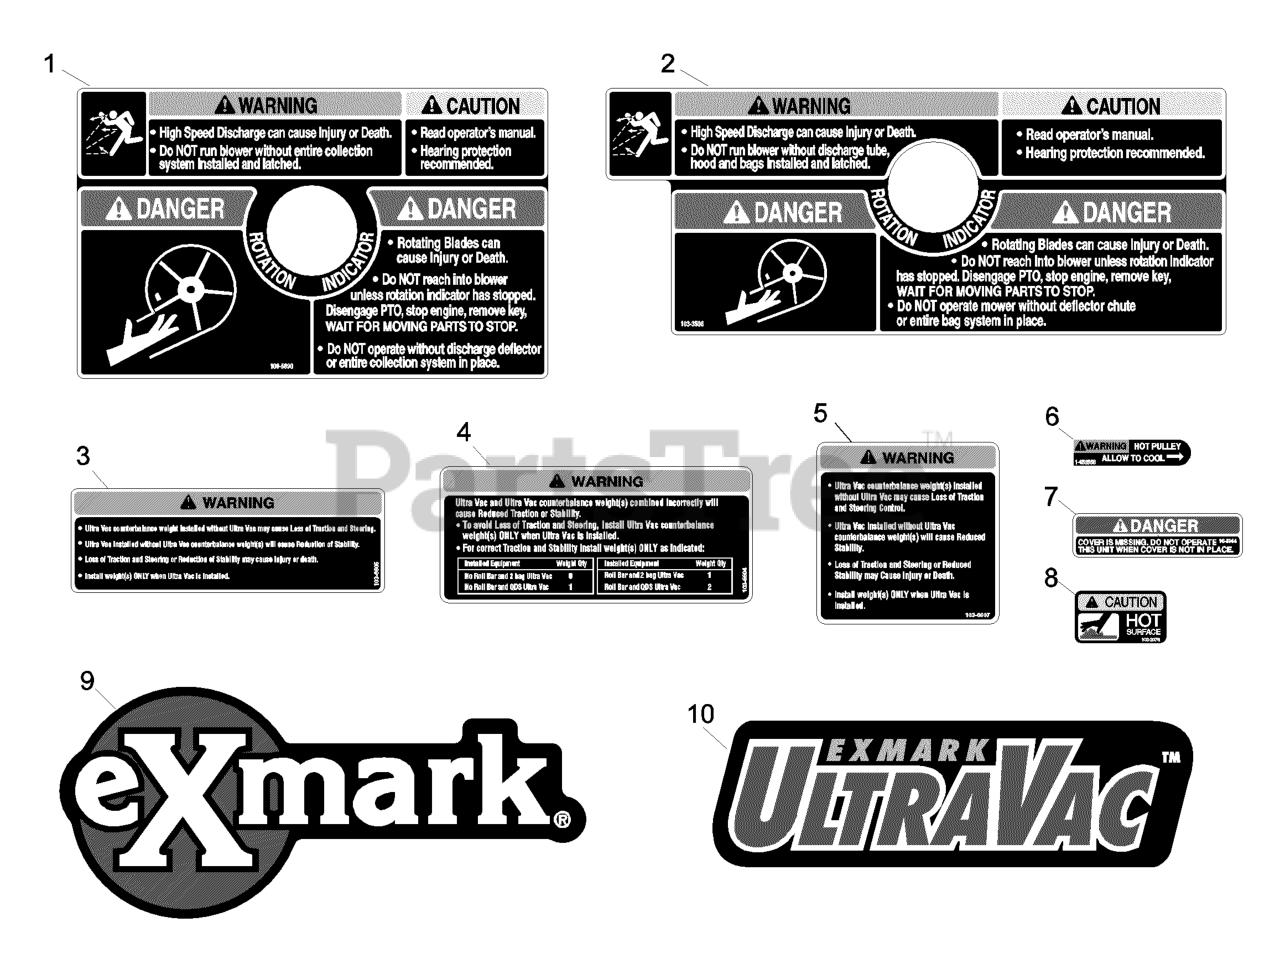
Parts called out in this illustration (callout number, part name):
1	DECAL-WARNING, BLOWER
2	DECAL-WARNING
3	DECAL,WEIGHT
4	DECAL,WEIGHT
5	DECAL,WEIGHT
6	DECAL-WARNING
7	DECAL-COVER, MISSING
8	DECAL-CAUTION
9	DECAL, EXMARK LOGO
10	DECAL, ULTRA VAC
